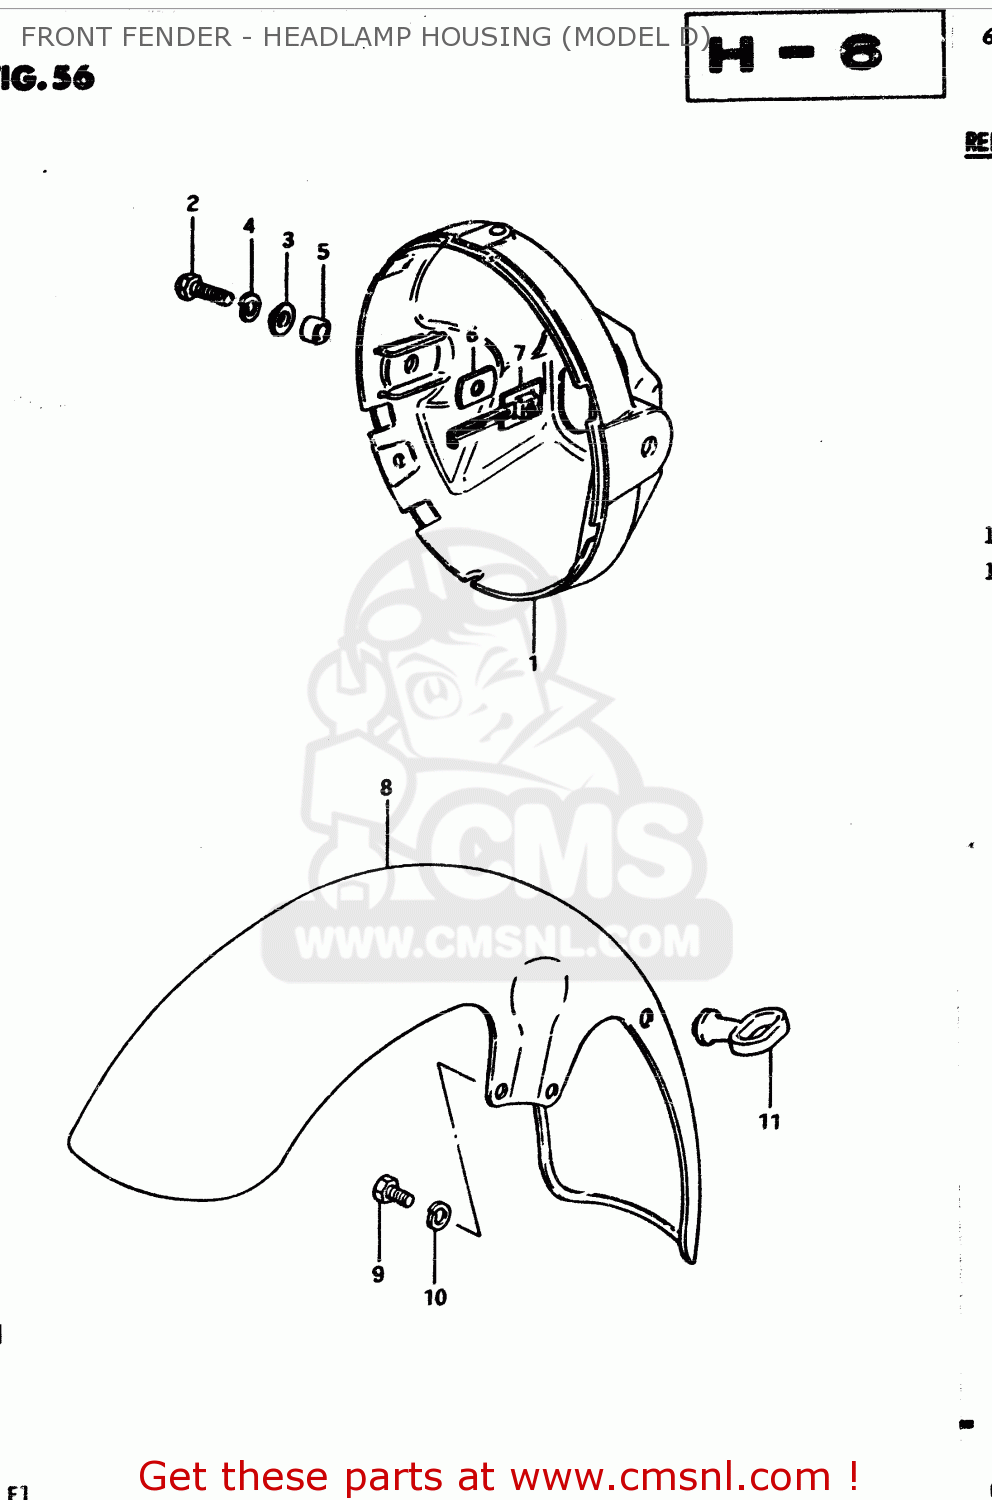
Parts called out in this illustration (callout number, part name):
1	HOUSING,HEADLAMP
2	BOLT
3	WASHER
4	LOCK WASHER
5	SPACER (8.8X12X7)
6	CUSHION
7	PLATE,HEADLAMP HOUSING
8	FENDER, FRONT
9	BOLT
10	LOCK WASHER
11	GUIDE,CABLE
